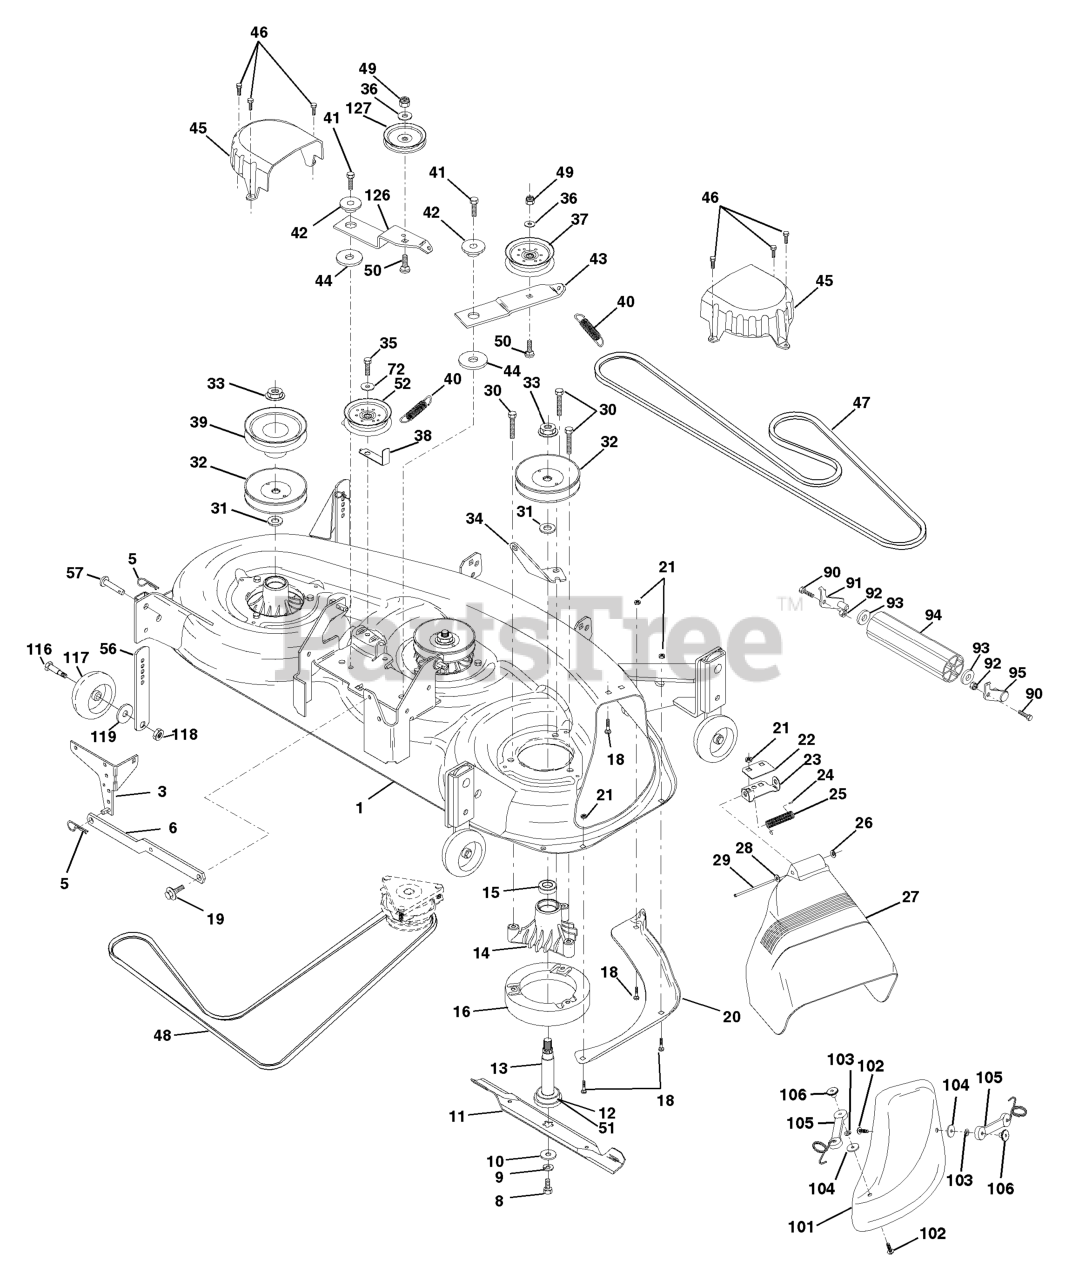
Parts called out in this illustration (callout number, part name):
1	DECK
3	BRACKET SWAY BAR
5	RETAINER-SPRNG RB
6	REAR SUSP ARM
8	BLADE BOLT
9	LOCKWASHER
10	WASHER.BLADE
11	MULCH BLADE
12	BEARING.BALL.#6204.(MANDREL)
13	SHAFT.ASM.W/BEARING
14	HOUSING.MANDREL.44/46" VENT
16	STRIPPER
18	BOLT
19	BOLT SHD 5/16-18
20	BAFFLE, VORTEX MOWER 46"
21	LOCKNUT
22	STIFFENER BRACKET
23	DEFLECTOR BRACKET
24	CAP-SLEEVE LT
25	TORSION SPRING
26	NUT PUSH M
27	DEFLECTOR SHIELD
28	Washer 11/32 x 5/8 x 16 Ga.
29	ROD.HINGE
30	SCREW THDROL ROLLING WASHER HD
31	WASHER
32	PULLEY, MANDREL
33	NUT
34	ANCHOR, SPRING DECK 46"
35	SCREW LT
36	WASHER
37	FLAT IDLER PULLEY
38	KEEPER.BELT.IDLER
39	PULLEY.DRIVEN.DECK.46"
40	SPRING.SEC.44"VEN
41	SCREW
42	SPACER RETAINER
43	ARM IDLER DECK 46"
44	HARDENED WASHER
45	COVER MANDREL 46
46	SCREW.1/4-20X5/8
47	BELT V SECONDARY
48	V-BELT PRIMARY 50"
50	BOLT.3/8-16X1.50
51	WASHER FELT
52	PULLEY IDLER FLAT 46 PRI DRIVE
56	BAR.ADJUST.WHEEL.ANTI.SCALP.BL
57	RIVET.PIN.HEAD.YELLOW.
72	WASHER
90	BOLT
91	BRACKET LH (A)
92	NUT
93	Washer 17/32 x 7/8 x 16 Ga.
94	NOSE ROLLER
95	BRACKET RH (B)
101	COVER.MULCH.46"3-BLADE.(2 2)
102	SCREW
103	LOCKWASHER #10
105	LATCH ASSY
106	WELDNUT
116	BOLT, SHOULDER
117	WHEEL GAGE DONUT
118	LOCKNUT
119	WASHER.5/16.FLAT.STE.STD.
126	ARM IDLER PRIM 46
127	PULLEY.IDLER.4.25
